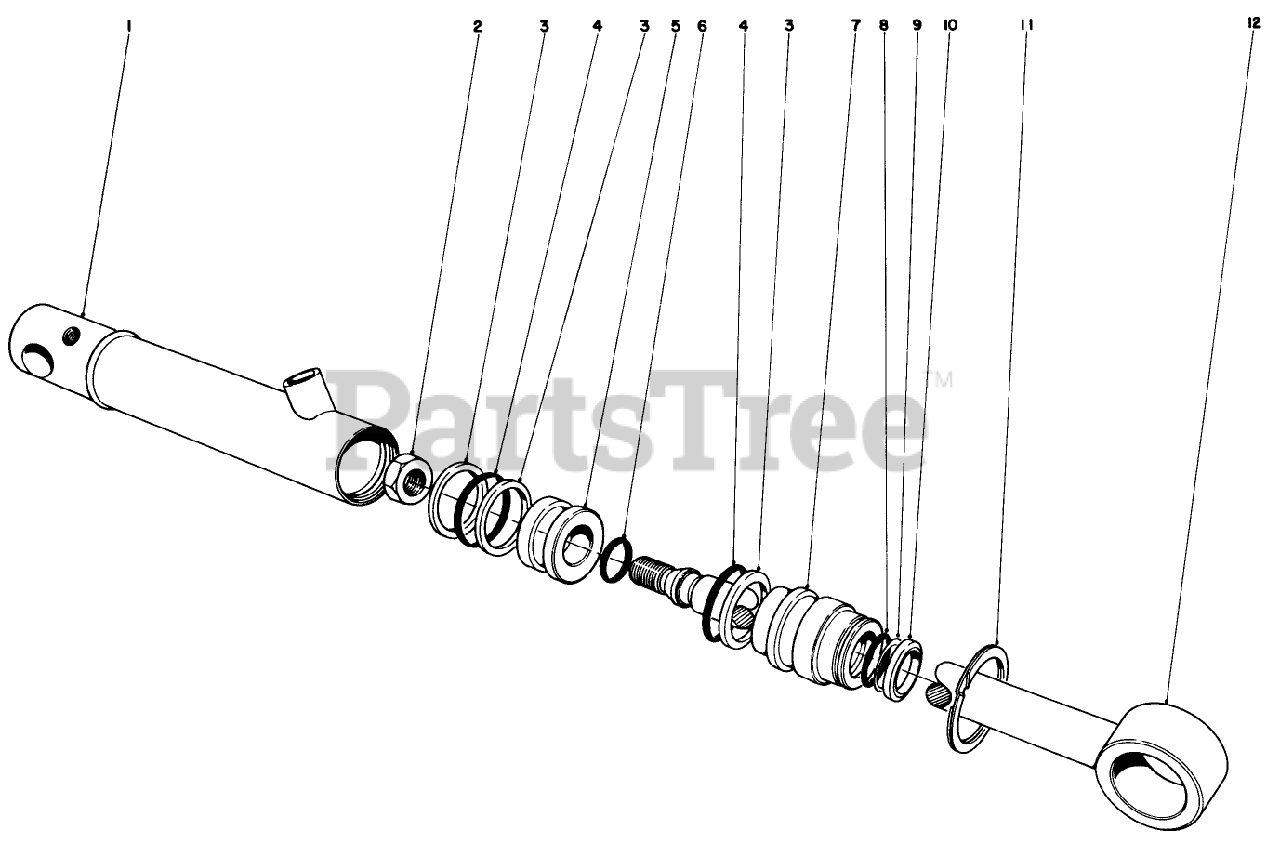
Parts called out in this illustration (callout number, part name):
1	Tube Assembly
3	Back Up Washer
4	O-Ring Piston
5	PISTON
9	Leather
10	Dust Seal
11	RING-RETAINING
